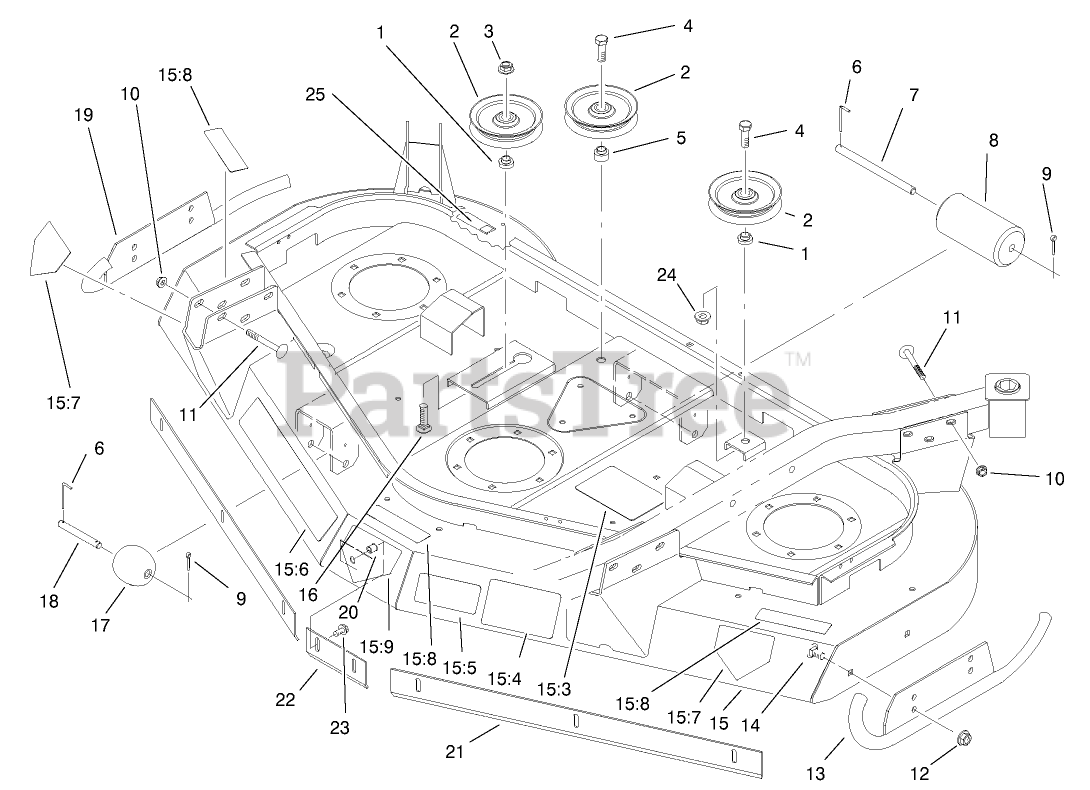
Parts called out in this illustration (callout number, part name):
1	SPACER-IDLER
2	PULLEY-IDLER
3	NUT-LOCK, NI
4	SCREW-HH
5	SPACER-IDLER, FLAT
6	PIN-SPECIAL
7	SHAFT-ROLLER
8	ROLLER-DECK
9	PIN-COTTER
10	NUT-HF
11	SCREW-CARR
12	NUT-HF
13	LH SKID ASM
14	SCREW-CARR
15	DECK ASM
15:3	DECAL-ROUTING, BELT
15:4	Decal-Warning
15:5	DECAL-TORQUE, BLADE BOLT
15:6	DECAL-GUARDIAN 62
15:7	DECAL-DANGER, CE
15:8	DECAL-DANGER
15:9	DECAL-DANGER
16	SCREW-CARR
17	ROLLER
18	SHAFT-ROLLER
19	RH SKID ASM
20	NUT-INSERT
21	BAFFLE-SIDE
22	BAFFLE-CENTER
23	SCREW-HHF
24	NUT-HF
25	Decal-Ansi
